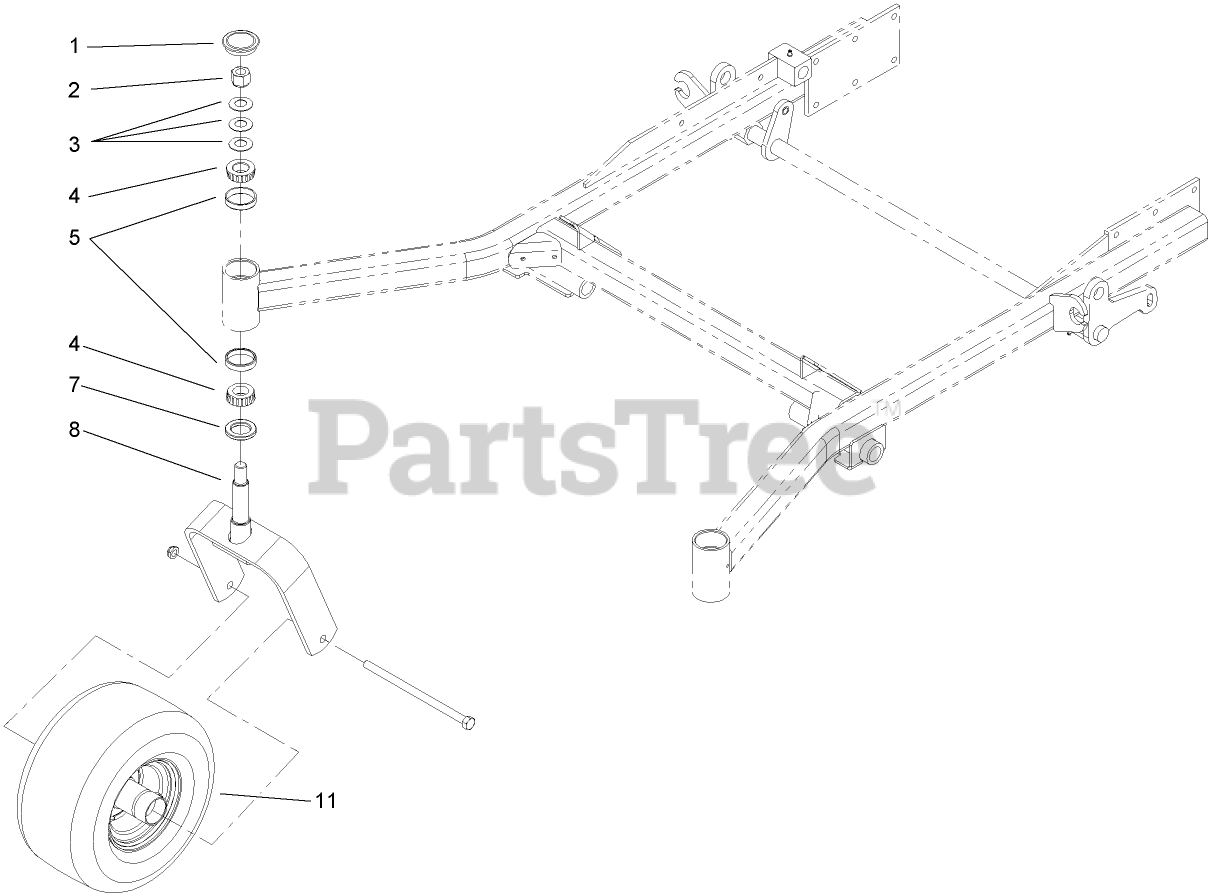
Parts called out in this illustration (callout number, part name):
1	CAP-GREASE
2	NUT-LOCK, NI
3	WASHER-BELLVILLE
4	BEARING-CONE, TAPERED
5	BEARING-CUP, TAPERED
7	SEAL-GREASE
8	CASTER-FORK
11	CASTOR WHEEL ASM
